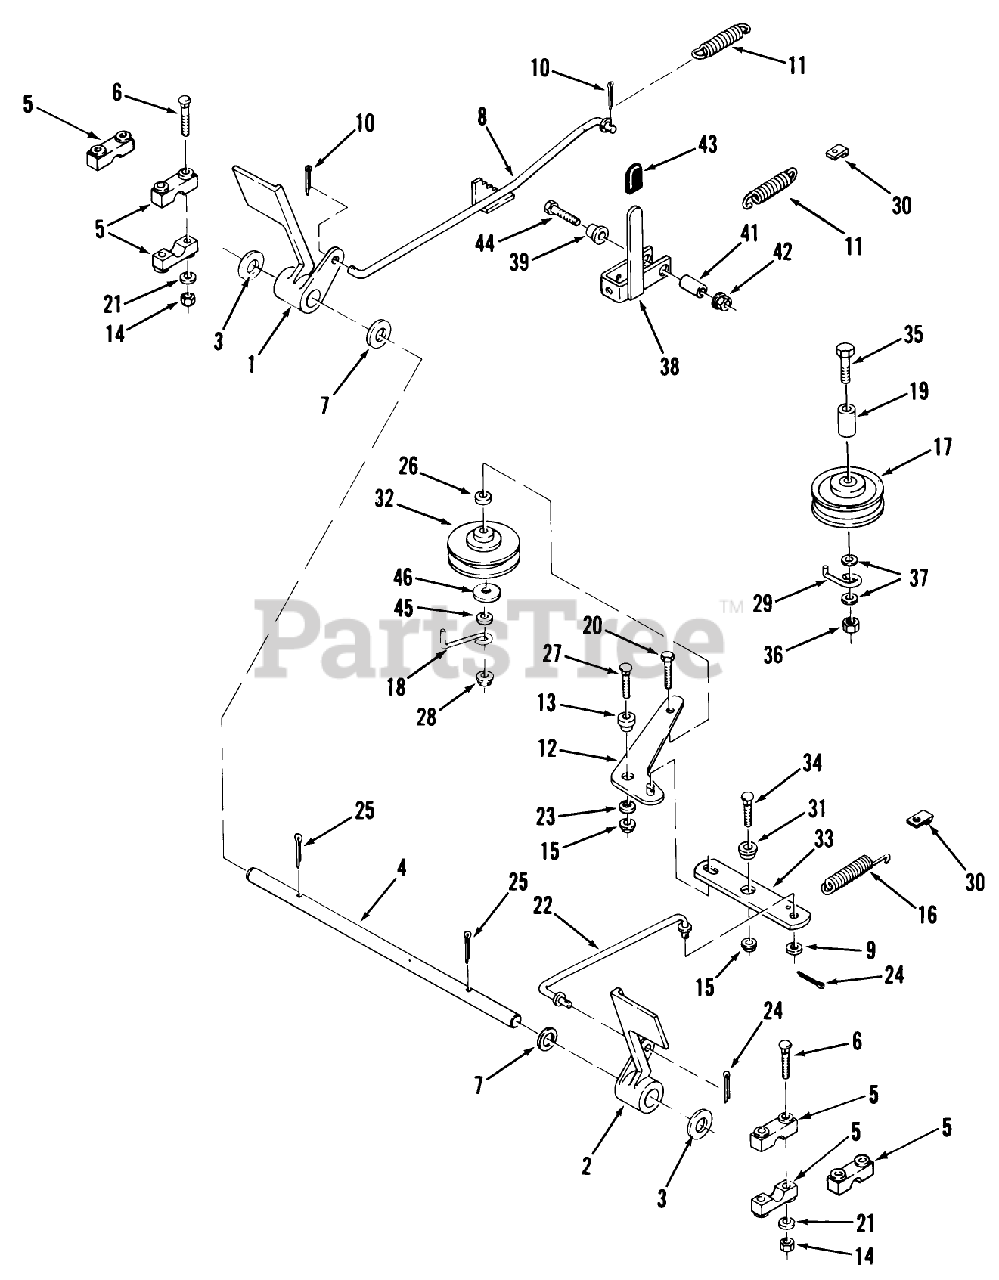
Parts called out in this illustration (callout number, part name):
1	PEDAL-BRAKE *R
3	WASHER-SPECIAL
9	WASHER 5/16 SAE
11	SPRING-EXTENSION
13	SPACER-IDLER ARM
16	SPRING
17	PULLEY-IDLER STATION
21	WASHER 5/16 SAE
22	ROD-CLUTCH *R
30	CLIP - SPRING
32	IDLER PULLEY
38	PAWL-HANDLE ASSY
39	SPACER
41	SPACER
43	GRIP
46	WASHER
